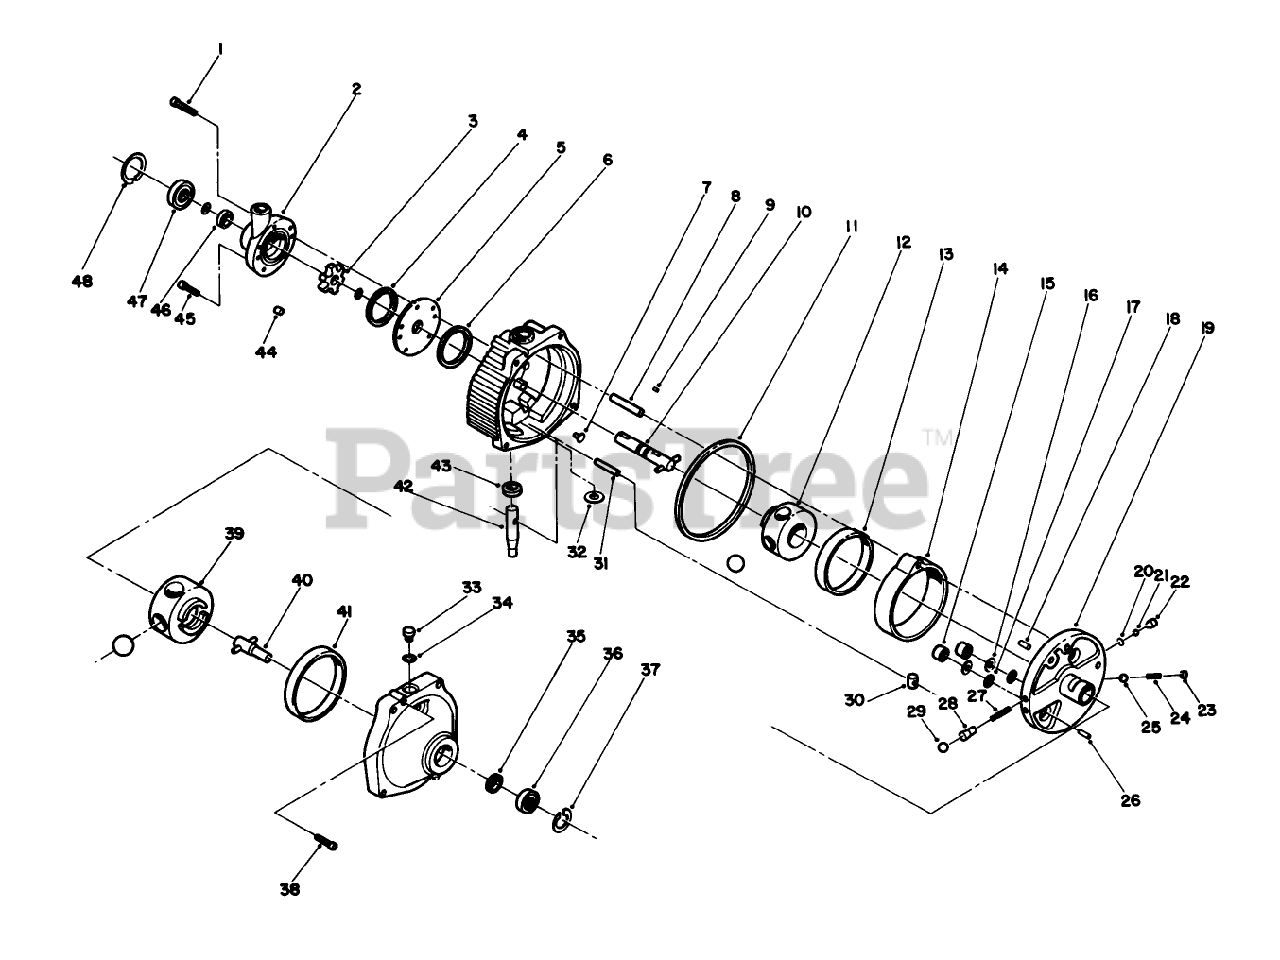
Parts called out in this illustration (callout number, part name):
1	CAPSCREW
2	CHARGE PUMP
3	CARRIER
5	PLATE
7	BUTTON
12	ROTOR
13	Pump Race
14	CAM RING ASM
15	PISTON
17	O-RING
19	PINTLE
24	SPRING
27	SPRING
30	INSERT
31	Dowel
32	Control Shaft Washer
33	PLUG ASM
34	O-RING
39	ROTOR
42	SHAFT KIT
45	SCREW-HH
46	SEAL-OIL
47	BEARING
